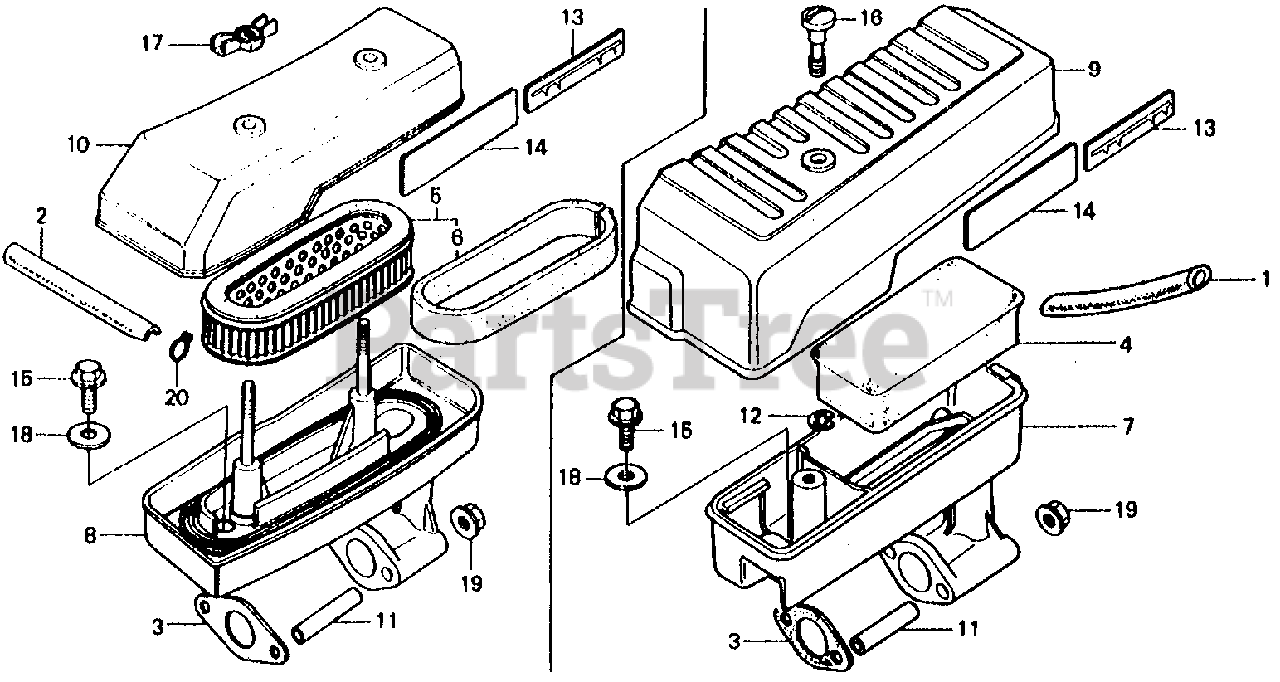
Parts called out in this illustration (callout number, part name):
1	TUBE, BREATHER
1	TUBE, BREATHER (Honda Code 0751420). (NOT AVAILABLE)
3	GASKET, AIR CLEANER (Honda Code 0636308). (NOT AVAILABLE)
3	GASKET, AIR CLEANER
4	ELEMENT, AIR CLEANER
7	HOUSING, AIR CLEANER
7	HOUSING, AIR CLEANER (Honda Code 0808097). (NOT AVAILABLE)
9	COVER, AIR CLEANER *NH31* (Honda Code 0672113). (MCKINLEY WHITE)
11	COLLAR, AIR CLEANER HOUSING
12	E-CLIP (Honda Code 0559518). (NOT AVAILABLE)
13	MARK, CONTROL
14	MARK, AIR CLEANER CAUTION
15	BOLT, FLANGE (6X12) (CT200)
16	BOLT, AIR CLEANER COVER
18	WASHER, HEADLIGHT CASE
19	NUT, FLANGE (6MM)
